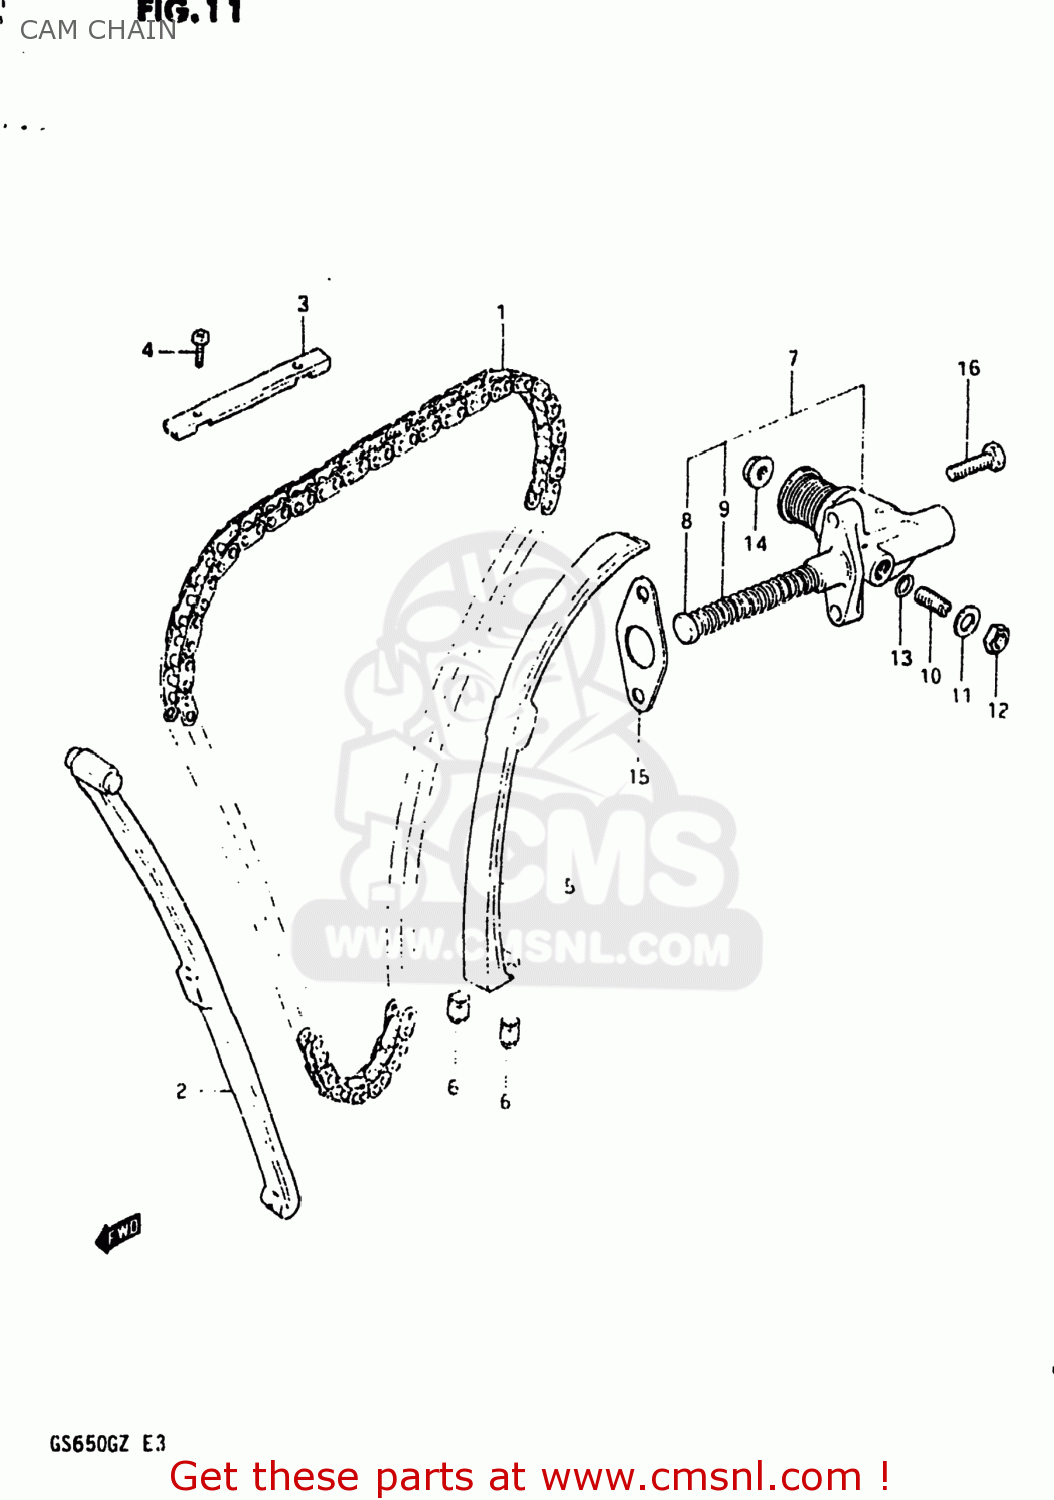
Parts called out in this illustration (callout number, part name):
1	CHAIN,CAMSHAFT DRIVE(120L)
2	GUIDE,CAM CHAIN
3	GUIDE,CAM CHAIN
4	SCREW
5	TENSIONER,CAM CHAIN
6	CUSHION,CAM CHAIN TENSIONER
7	ADJUSTER ASSEMBLY,TENSIONER
8	ROD,PUSH
9	SPRING
10	SCREW
11	WASHER
12	NUT
13	O-RING
14	NUT
15	GASKET,TENSIONER ADJUSTER (MCA)
16	SCREW (6X25)
